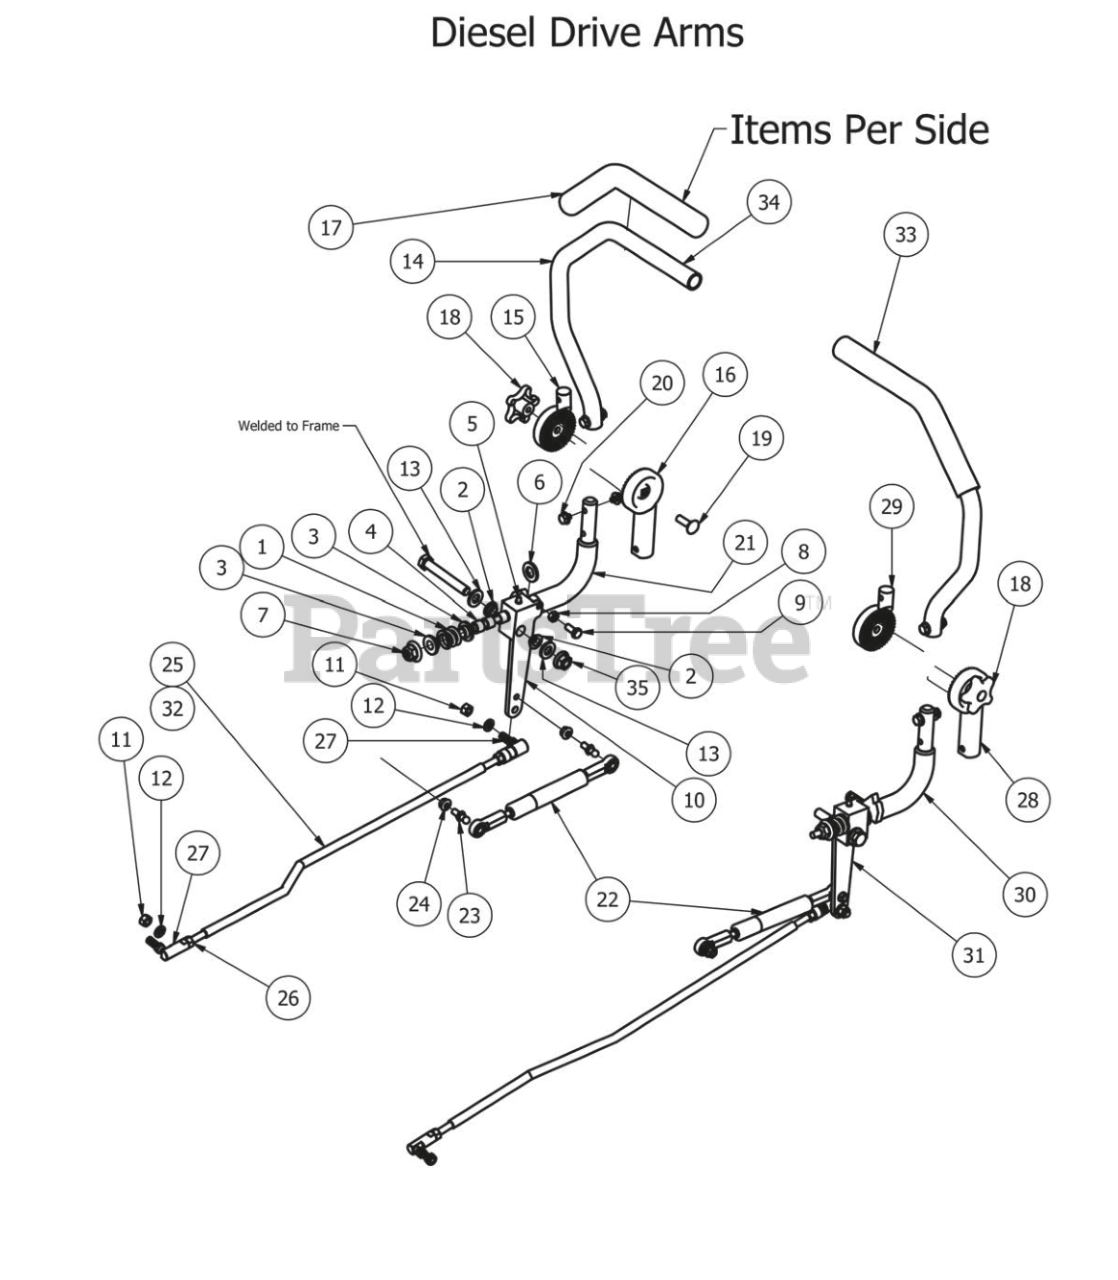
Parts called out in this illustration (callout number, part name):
1	Drive Lever Spring
2	Bushing for 2012 Drive Arms
3	.515 ID Nylon Shoulder Washer
4	.507 ID Nylon Bushing
5	1/4" Drive in Grease Fitting
6	.635 ID Plastic Washer
7	1/2-13 Nylon Flange Nut-Orange
9	5/16" x 3/4" Hex Bolt
10	Drive Arm Lever Housing (Left)
11	3/8" Fine Threaded Jam Nut
12	3/8" Lock Washer
13	.505x1x.125 Oil Impregnated washer
14	Upper Tube-Adjustable Steering
15	Upper adjuster-Steering Arm- Left
16	Lower Adjuster - Steering Arm- Left
17	Black Steering Grip
18	Black Knob for Adjustable Steering Arm
19	3/8" x 1 1/4" Carriage Bolt
20	5/16-18 1/2 HWH Bolt-Steering
21	Steering Arm Elbow - Left
23	10mm Damper Ball Stud-Steering
24	5/16" Flange Nut
25	Streering Push Rod -28Hp Diesel Push Rod
26	3/8" Fine Threaded Jam Nut
27	3/8-24 Ball Joint
28	Lower Adjuster - Steering Arm- Right
29	Upper Adjust Steering Arm- Right
30	Steering Arm Elbow - Right
31	Drive Arm Lever Housing Right
32	Steering Push Rod - 35HP Diesel
33	Adjustable Steering Arm-Right Assembly-Componets 14,17,18,19,20,28,29
34	Adjustable Steering Arm-Left Assembly-Componets 14,15,16,17,18,19,20
35	1/2-13 Hex Flange (GR.G) ZC
